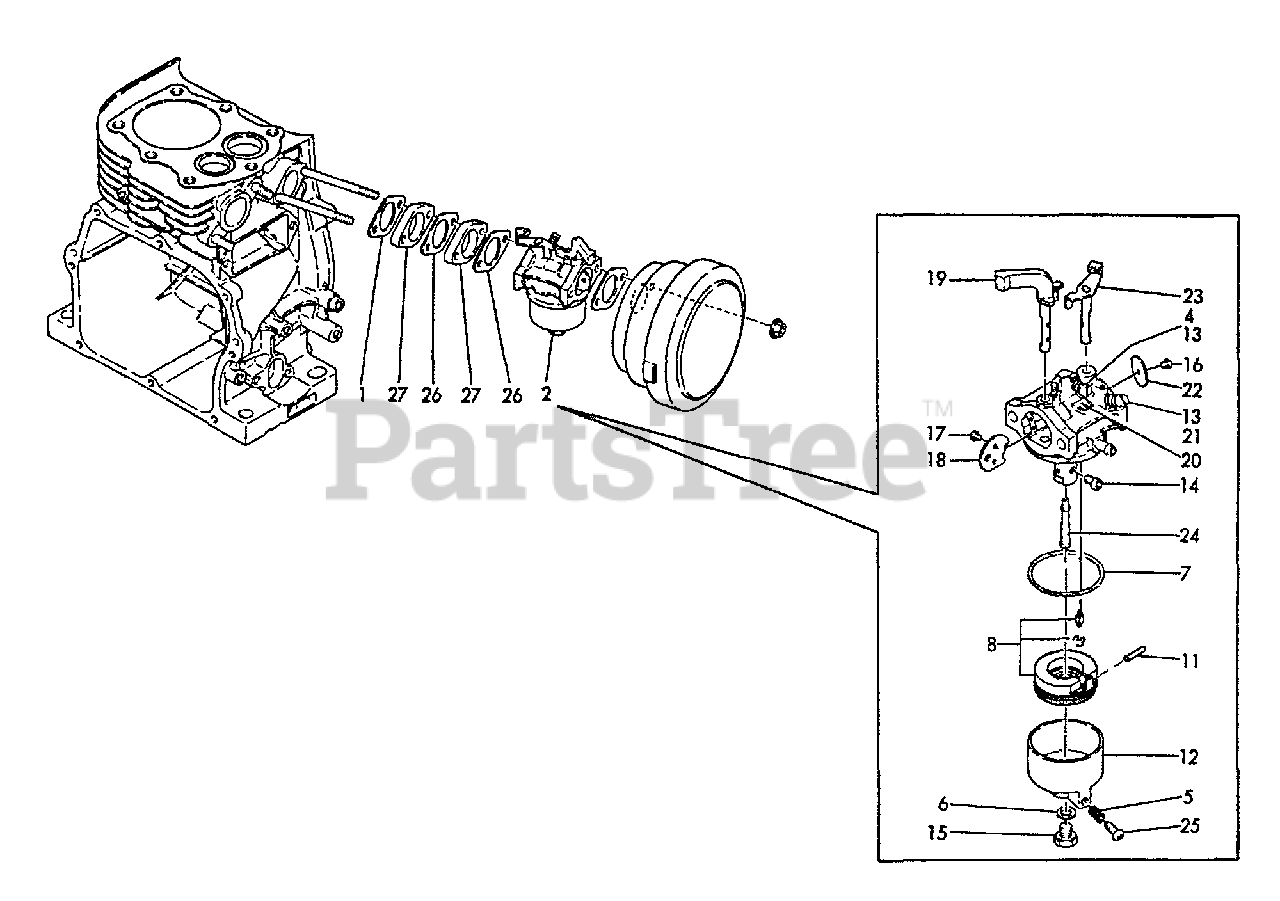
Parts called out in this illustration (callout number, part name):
1	GASKET, EXHAUST
2	CARBURETOR
4	SCREW
6	GASKET
7	GASKET
8	NEEDLE ASSY (RUBBER)
11	PIN
12	BODY, FLOAT CHAMBER
14	JET, MAIN
15	BOLT
16	SCREW
17	SCREW
18	VALVE
19	SHAFT, CHOKE
20	JET, PILOT
21	SCREW, PILOT
22	VALVE, THROTTLE
23	SHAFT ASSY, THROTTLE
24	NOZZLE, MAIN
25	SCREW
26	GASKET, INTAKE
27	SPACER
